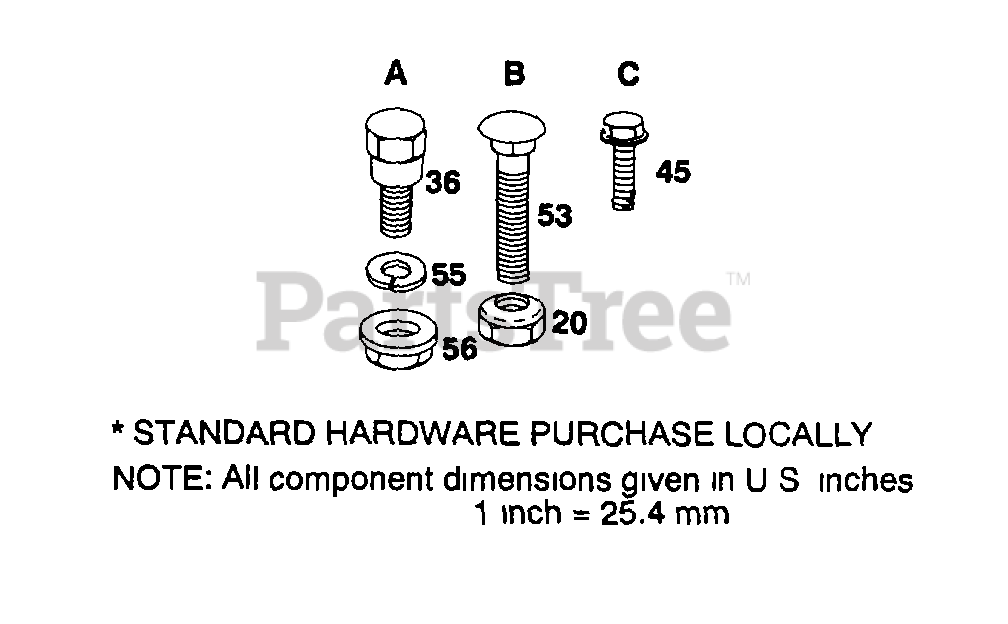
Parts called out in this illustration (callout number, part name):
36	"BOLT, SHOULDER LT"
45	SCREW
55	WASHER T
56	NUT SPECIAL T
